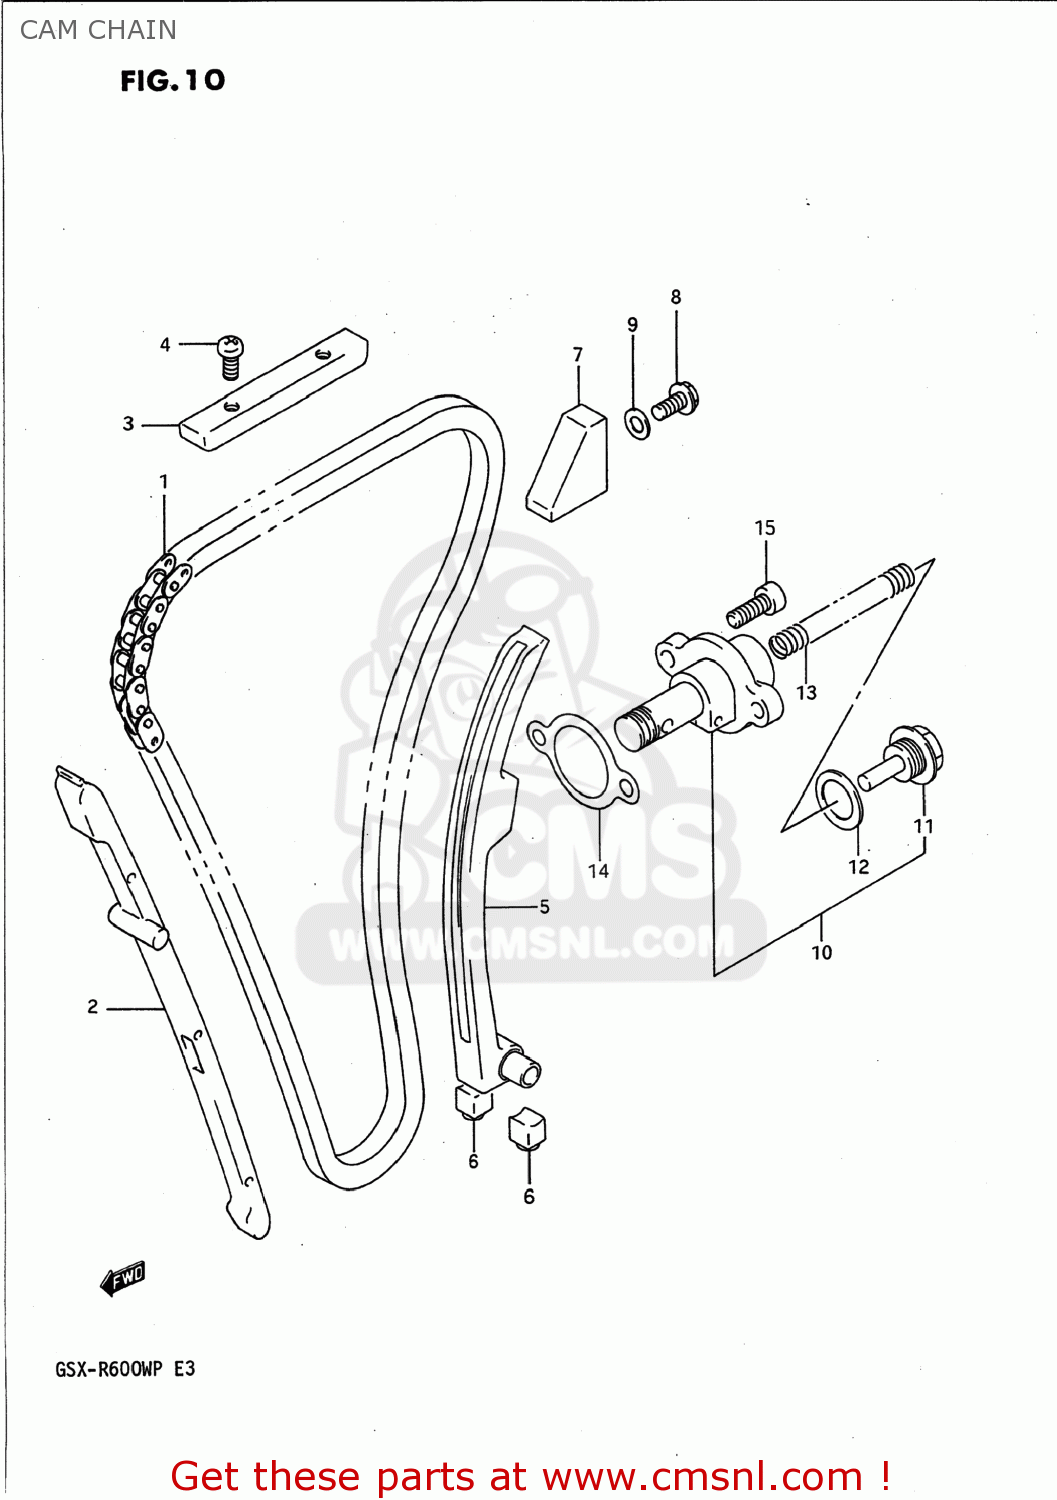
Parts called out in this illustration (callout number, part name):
1	CHAIN,CAMSHAFT DRIVE
2	GUIDE,CAM CHAIN NO.1
3	GUIDE,CAM CHAIN NO.2
4	SCREW
5	TENSIONER,CAM CHAIN
6	CUSHION,CAM CHAIN TENSIONER
7	GUIDE,CAM CHAIN NO.3
8	BOLT 6X12
9	GASKET(5.8X13X1.2) (NAS)
10	ADJUSTER ASSEMBLY,TENSIONER
11	PLUG
12	GASKET (NAS)
13	SPRING
14	GASKET,TENSIONER ADJUSTER (NAS)
15	BOLT
